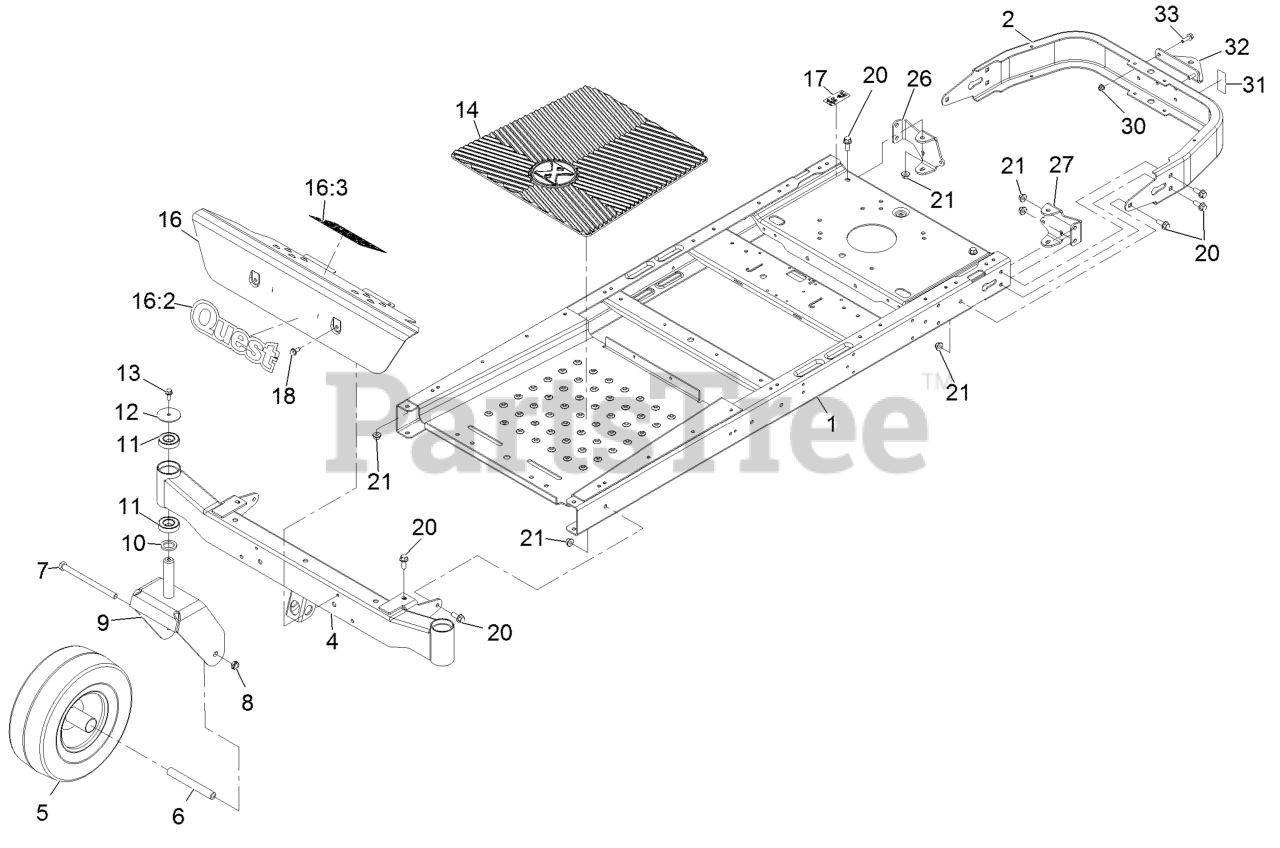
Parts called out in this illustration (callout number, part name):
2	BUMPER-REAR
4	AXLE-FRONT
5	CASTER WHEEL ASM
6	BUSHING-SPANNER
7	SCREW-HH
8	NUT-HEX
9	FORK-CASTER
10	WASHER-THRUST
11	BEARING-BALL
13	SCREW-HHF
14	MAT-FLOOR
16	FOOTREST ASM
17	DECAL-BYPASS
18	Screw-HWH 5/16-18 X 3/4 Tf
20	SCREW-HHF 3/8-16 X 1
21	NUT-HF, NI
26	MOUNT-HYDRO, REAR (RH)
27	MOUNT-HYDRO, REAR (LH)
30	NUT-HF, NI
32	BRACKET-HITCH
33	SCREW-HHF
